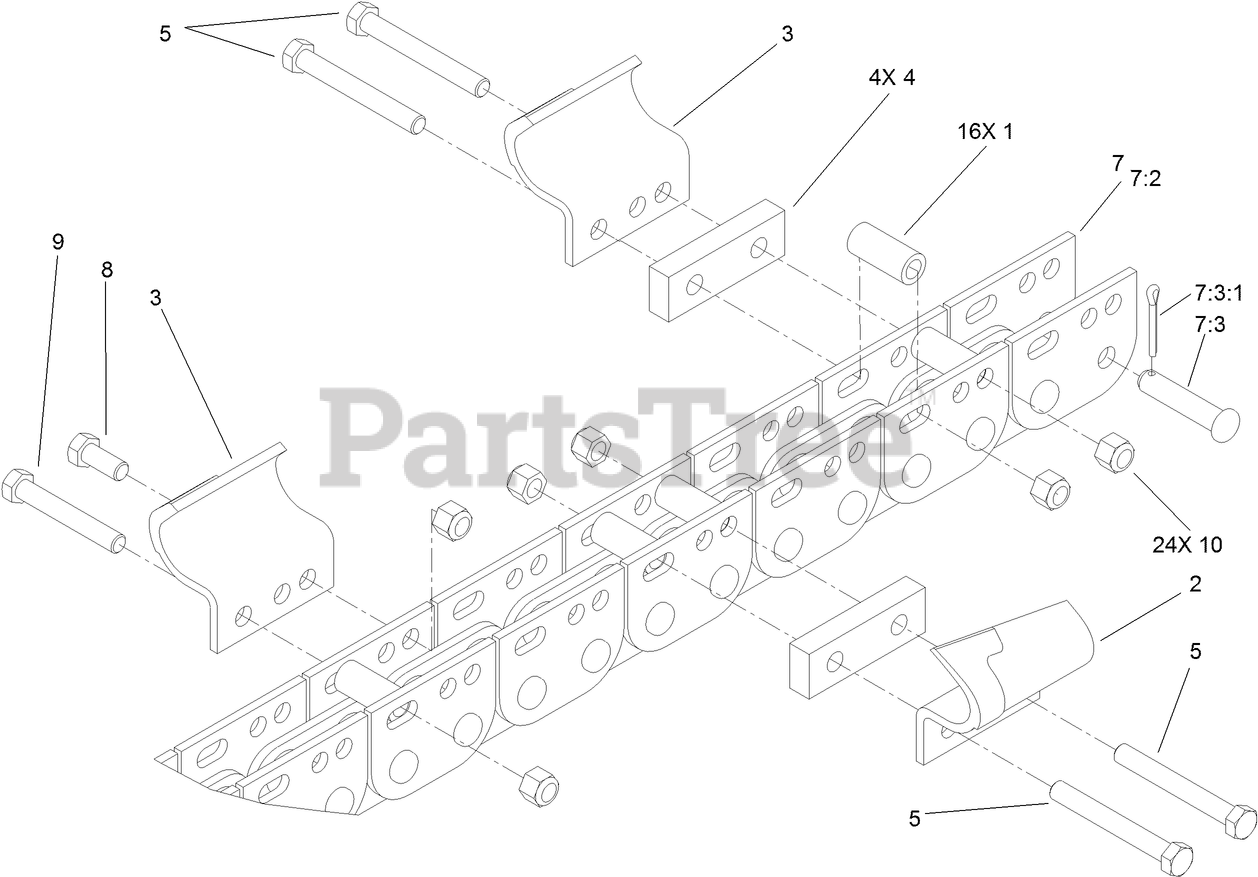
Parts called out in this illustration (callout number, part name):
1	SPACER-TUBE
2	TOOTH-SOIL, LH
3	TOOTH-SOIL, RH
4	SPACER-CUT, 5 INCH
5	SCREW-HH
7	CHAIN-BARE, 24 STATION
7:2	LINK REPAIR KIT
7:3	PIN-CONNECTING (61MM)
7:3:1	PIN-COTTER
9	SCREW-HH
10	NUT-HEX
